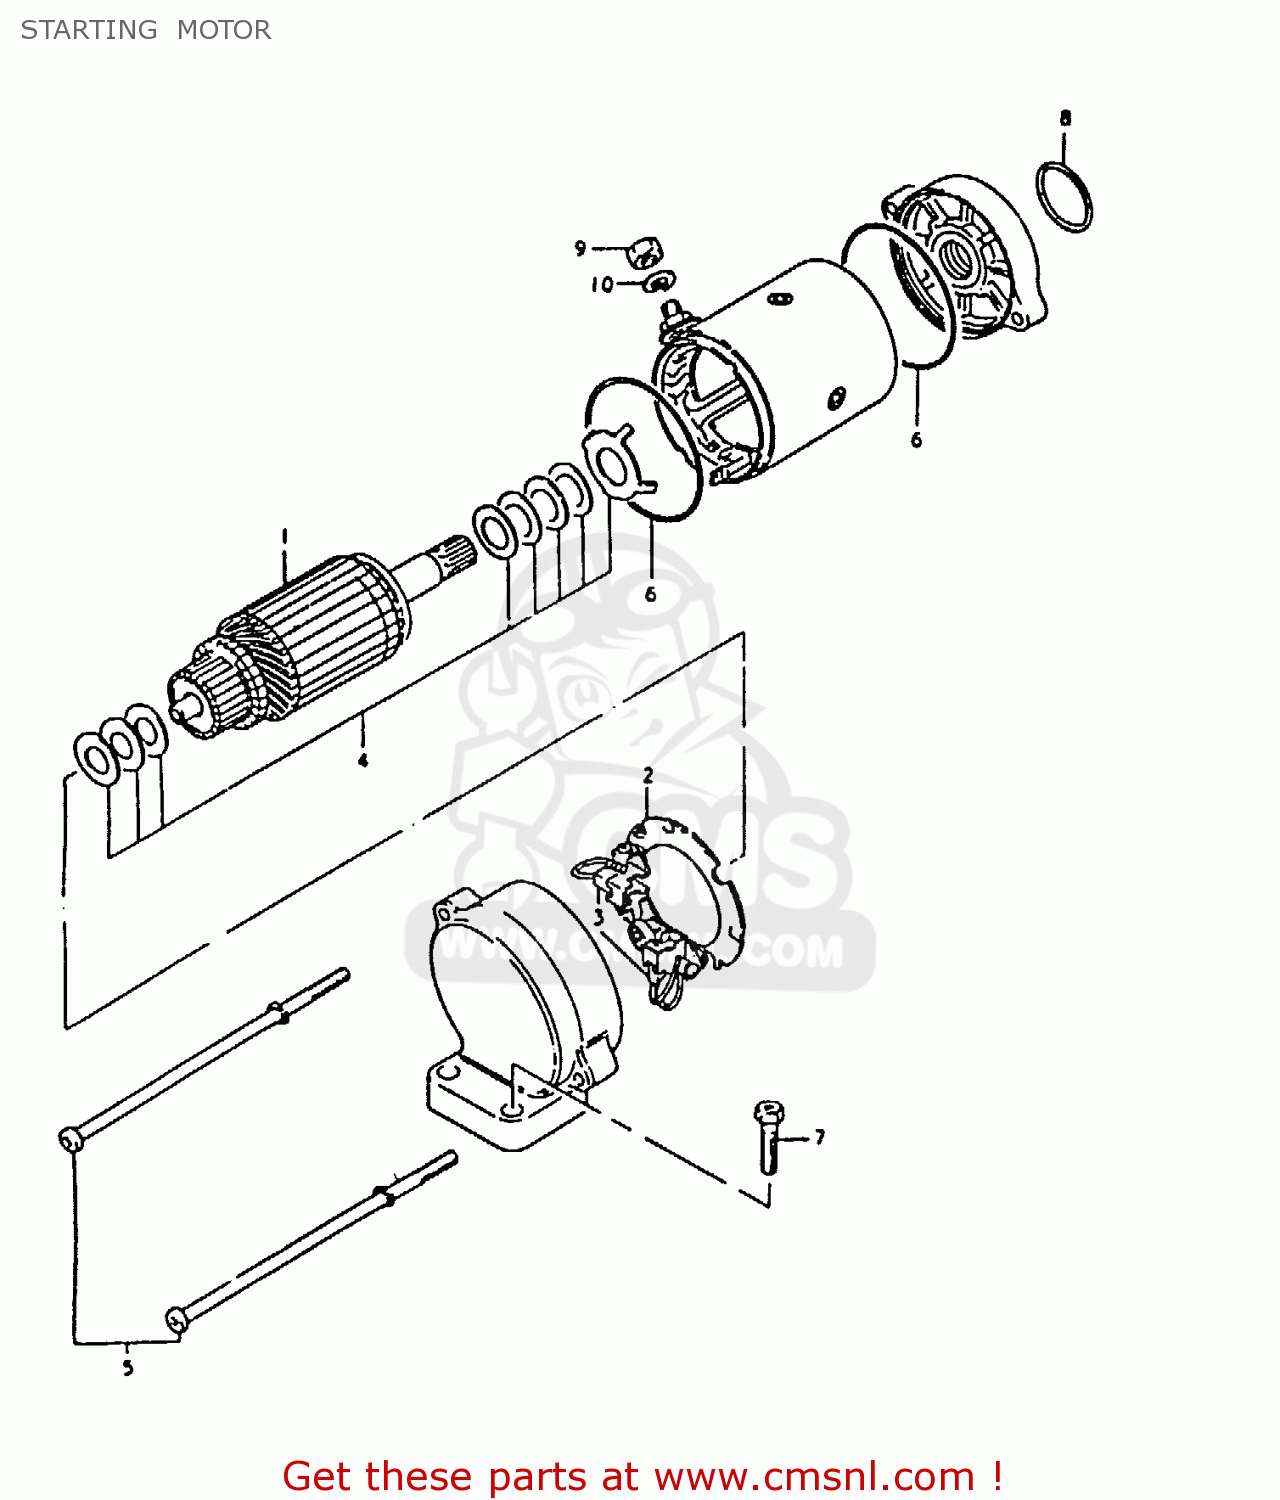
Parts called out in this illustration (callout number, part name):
1	ARMATURE
2	HOLDER ASSY
3	BRUSH SET
4	SHIM SET
5	BOLT,STARTING MOTOR HOUSING
6	O RING
7	SCREW (6X25)
8	O RING(D:2,ID:24.5)
9	NUT 6MM
10	LOCK WASHER
